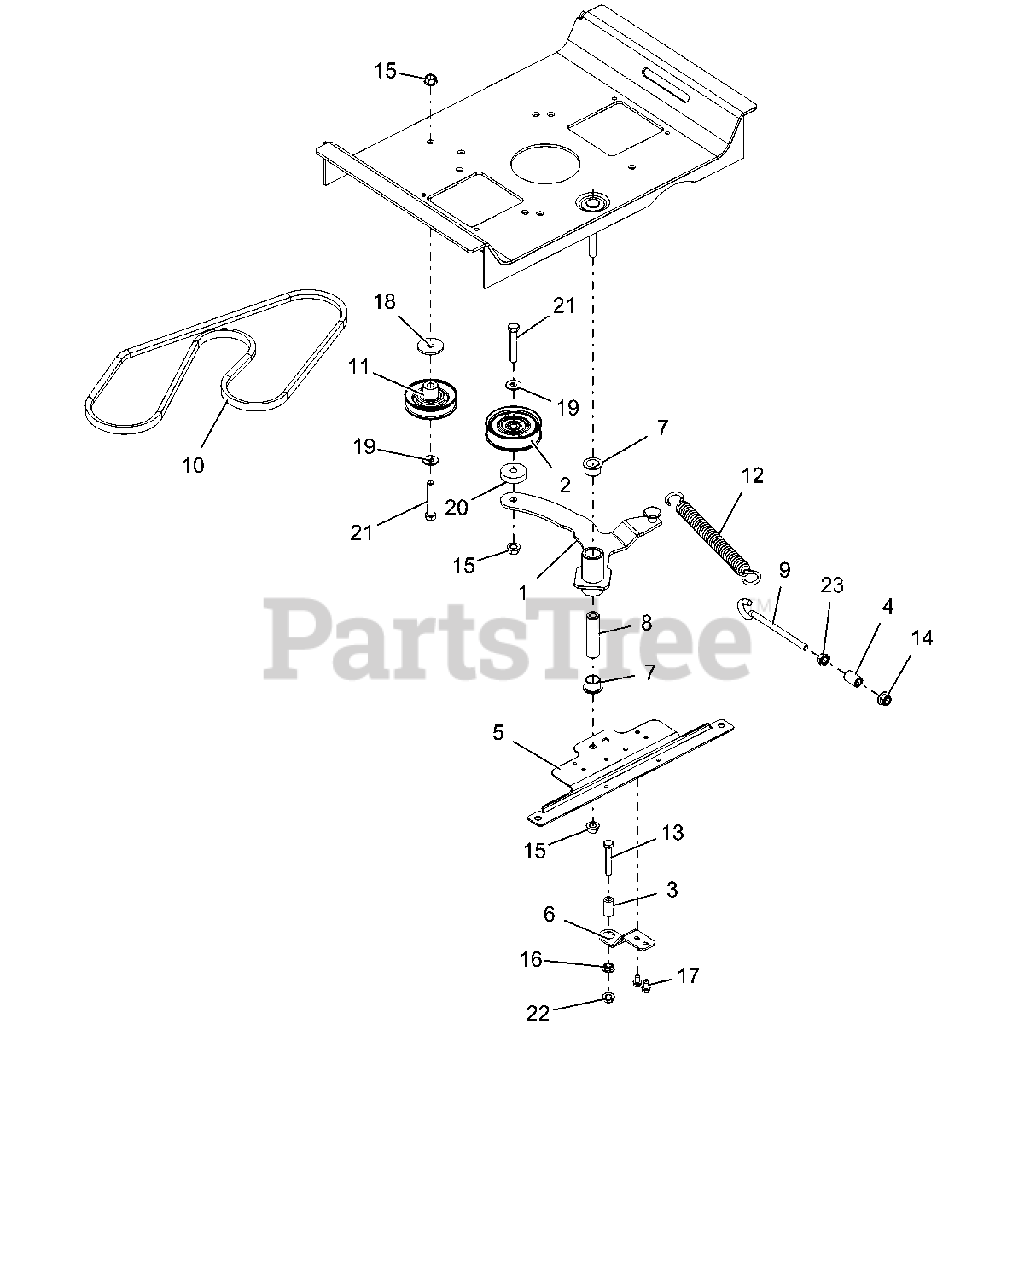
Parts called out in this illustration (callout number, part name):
1	WLDMT, IDLER GROUND DRIVE
2	IDLER, FLAT - 3.05" X .75"
3	SPCR, RUBBER 5/16 ID X 1.0 LG
4	SPCR, .375X.625X.970
5	BRKT, DRIVE IDLER MTG
6	BRKT, CLUTCH STOP (XL) (BLACK)
7	BSHG, FLANGE 0.75 X 0.875 X 0.625 X 0.125
8	BSHG, SLV .380x.750x2.53
9	BOLT, EYE .38-16X6.00 .62 DIA
10	V-Belt, A-RAW EDGE
11	ASM, 3.00" V IDLER
12	SPRG, EXTENSION - SWIVEL
13	BLT-HEX .31-18X2.00 GR5 YWZC
14	NUT-LK-NYL-FLG .38-16 YWZC
15	NUT, LK-TOP-FLG .38-16 YWZC
16	@NUT-SPNLK-FLG .312-18 YWZC
17	SCR-TAP .25-20X.50 HWH TR YWZ
18	WSHR-FL-STL .380X1.50X.125 YWZC
19	WSHR-FL-STL.38X.875X.083 YWZC
20	SPCR, .39X1.50X.380
21	BLT-HEX .38-16X2.25 GR5 YWZC
22	NUT, LK-TOP-FLG .312-18 YWZC
23	@NUT-SPNLK-FLG .375-16 YWZC
